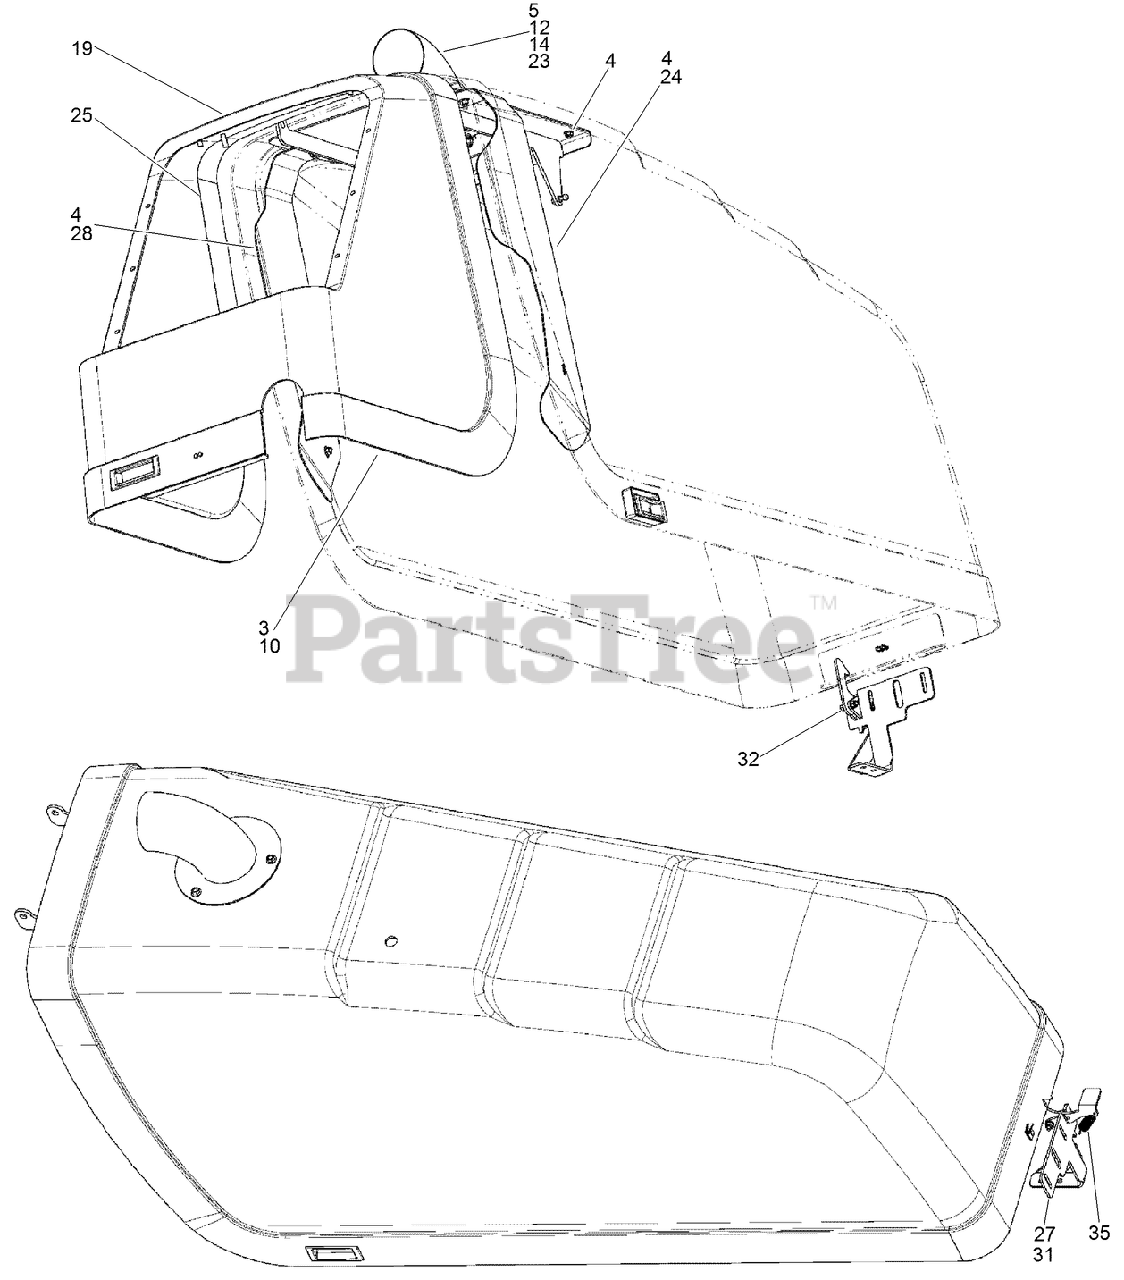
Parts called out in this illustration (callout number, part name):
3	NUT - Prev Trq 5/16 GRB ZND Direct
4	NUT-Serr Flg 3/8-16 UNC GR5 ZND
5	WASHER - .562 x 1.375 x .109 in CST ZND
10	STUD-BALL
12	NUT-FLANGE, NYLOCK
14	SCREW-HH
19	ASSEMBLY - Front Hood Mount
23	ASSEMBLY - Exhause Stack
24	PLATE - Guide
25	ASSEMBLY - Front Hood
27	NUT-#10-24 KEPS
28	PLATE - Guide
31	SCREW - Hex Hd #10 - 24 x 0.875 CST PHC
32	SCREW, METRIC FLANGE w/BODY - M8 x 35
35	SPRING-TENSION
